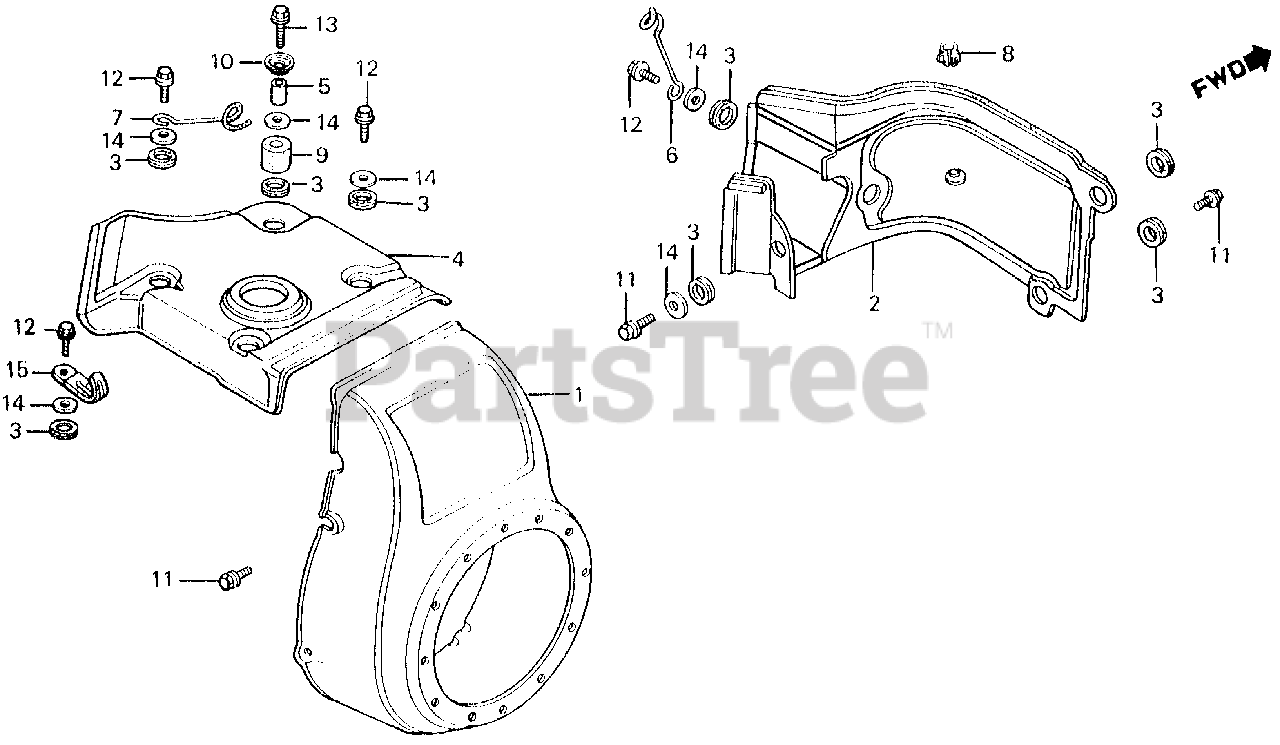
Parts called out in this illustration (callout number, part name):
1	COVER, FAN *R8* (BRIGHT RED) (NOT AVAILABLE)
2	SHROUD *R8* (BRIGHT RED)
3	RUBBER, MOUNTING
4	COVER, TOP *R8* (BRIGHT RED)
5	COLLAR, IGNITION COIL SETTING
6	CLAMP, IGNITION TUBE
7	CLAMP, IGNITION TUBE
8	CLIP, IGNITION WIRE (8MM)
9	RUBBER, STOPPER
10	PLATE, STOPPER
11	BOLT, FLANGE (6X12) (CT200)
12	BOLT, FLANGE (6X14)
13	BOLT, FLANGE (6X32)
14	WASHER, FLAT (20MM)
